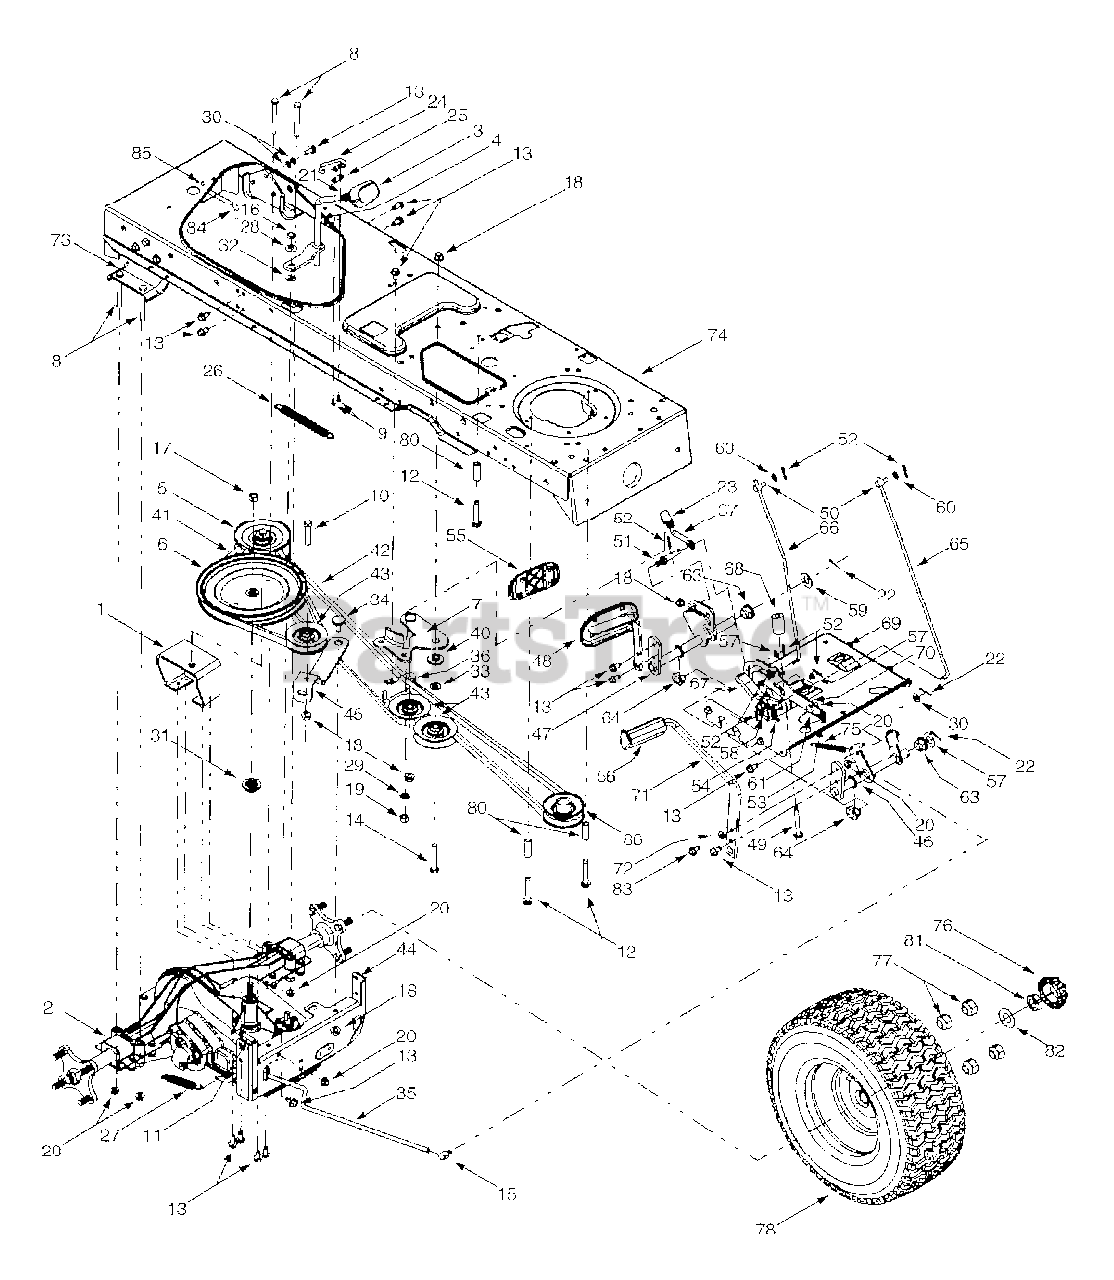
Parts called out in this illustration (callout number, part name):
1	Variable-speed Bracket Assembly
2	Two-speed Transmission Assembly
3	Shfter Knob
4	Shift Lever
5	Variable-speed Pulley Assembly
6	Transmission Pulley, 8.5
7	Double-idler Bracket
8	Hex Cap Screw, 5/16-18 x 2.75
9	Self Tapping Screw, #8-18 x.5
10	Hex Cap Screw, 3/8-16 x 1.75
11	Hex Cap Screw, 5/16-18 x 1.5
12	Self-tapping Screw, 1/4-20 x 1.25
13	Self Tapping Screw, 5/16-18 x .625
14	Hex Cap Screw, 3/8-16 x 2.25
15	Ferrule, 5/16 x .312 Dia.
16	Hex Jam Nut, 3/8-16
17	Hex Flange Nut, 7/16-20
18	Flange Lock Nut, 3/8-16
19	Hex Nut, 3/8-16
20	Flange Lock Nut, 5/16-18
21	Hex Jam Nut, 3/8-16
22	Cotter Pin
23	Ball Joint, 3/8-24
24	Spring Switch
25	Insulator Nut Plate
26	Extension Spring, .62 Dia. x 6.12
27	Extension Spring, .59 OD x 4.0
28	Bell Washer, .401 x .870 x .063
29	Lock Washer, 3/8
30	Flat Washer, 5/16
31	Pulley Hub, 1/2 Spline
32	Flat Washer, .44 x .75 x .06
33	Flat Washer, .407 x .812 x .135
34	Shoulder Screw, .625 Dia. x .21
35	Brake Rod
36	Belt Guard
37	Idler Adjustment Rod, 3/8
40	Shoulder Spacer, .380 ID
41	Variable-speed Belt
42	Drive Belt
43	Flat Idler, 2.75 OD
46	Brake Control Shaft Assembly
47	Speed Control Shaft Assembly
48	Drive Pedal Assembly
49	Self Tapping Screw, 5/16-18 x 2.5
50	Ferrule, 1/4-20
51	Pin, 3/8-16 x 2.43
52	Cotter Pin
53	Compression Spring, .34 OD x 1.0
54	Extension Spring, .5 OD x 1.41
55	Drive Pedal Pad
56	Brake Pedal Pad
57	Flat Washer, .281 x .5 x .0625
58	Flat Washer, 9/32 x 1/2 x 1/16
59	Flat Washer, .64 x 1.24 x .06
60	Flat Washer, .344 x .062 x .03
61	Shoulder Screw, .437 x 1.62
63	Hex Flange Bearing
64	Split Hex Flange Bearing
65	Cruise Control Rod
66	Brake Lock Control Rod
67	Cruise Latch
68	Spacer, 5/16 x 1.54
70	Drive Lockout Bracket
76	Hub Cap
77	Lug Nut, 7/16-14
80	Spacer, .372 x .26 x 1.03
81	Jam Nut, 3/4-16
82	Flat Washer, .78 x 1.59 x .06
83	Hex Screw, 5/16-18 x .75
84	Transmission Belt Guard Rod
85	Self Tapping Screw, 1/4-20 x .5
86	Engine Pulley, 3.56"
